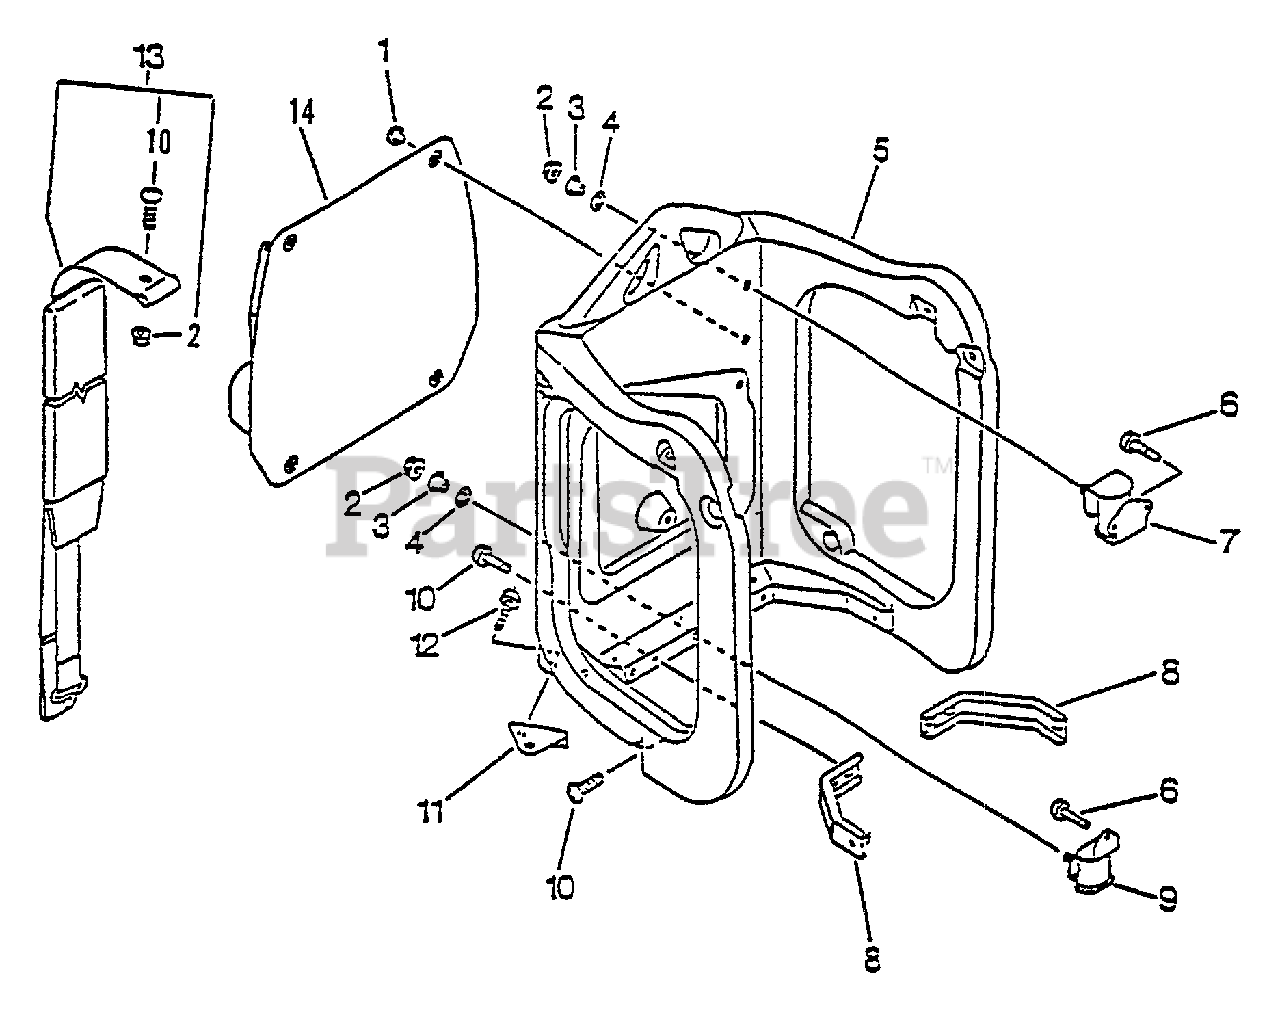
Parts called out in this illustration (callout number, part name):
2	NUT, FLANGE M5
5	FRAME, BACKPACK
6	SCREW 5×16
8	CONNECTOR, FRAME
9	CUSHION
10	SCREW - 5×14
11	BRACKET, HANGER
12	SCREW 5×20
13	STRAP, BACKPACK
14	CUSHION, BACKPACK
